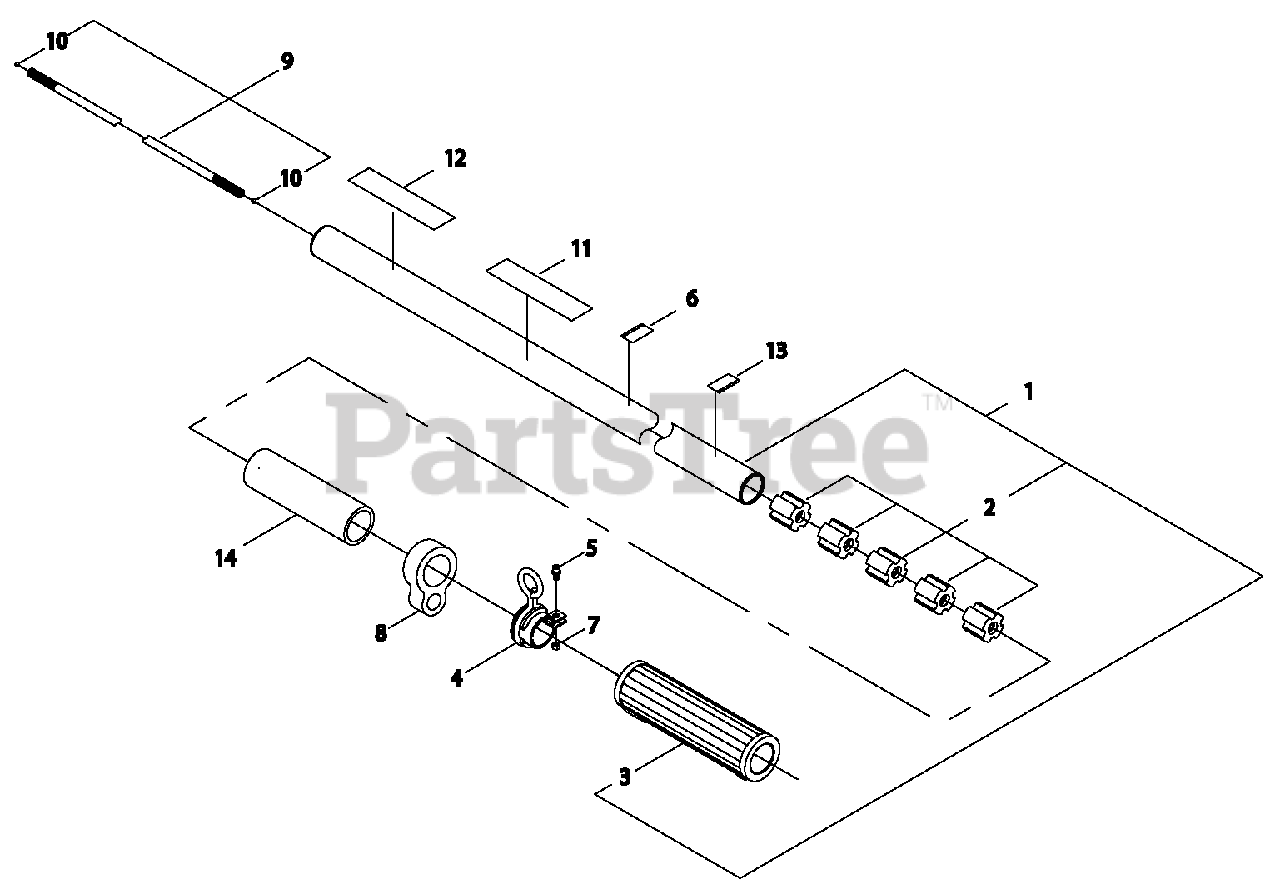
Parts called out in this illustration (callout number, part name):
1	MAIN PIPE ASSY
2	BUSHING
3	GRIP
4	HANGER ASSY
5	SCREW - 5X12
6	LABEL - HANDLE LOCATION
7	NUT - 5
8	BAND
9	DRIVESHAFT ASSY
10	STOPPER
11	LABEL - CAUTION
12	LABEL - SHINDAIWA PROFESSIONAL
13	LABEL - ALIGNMENT
14	PROTECTOR
